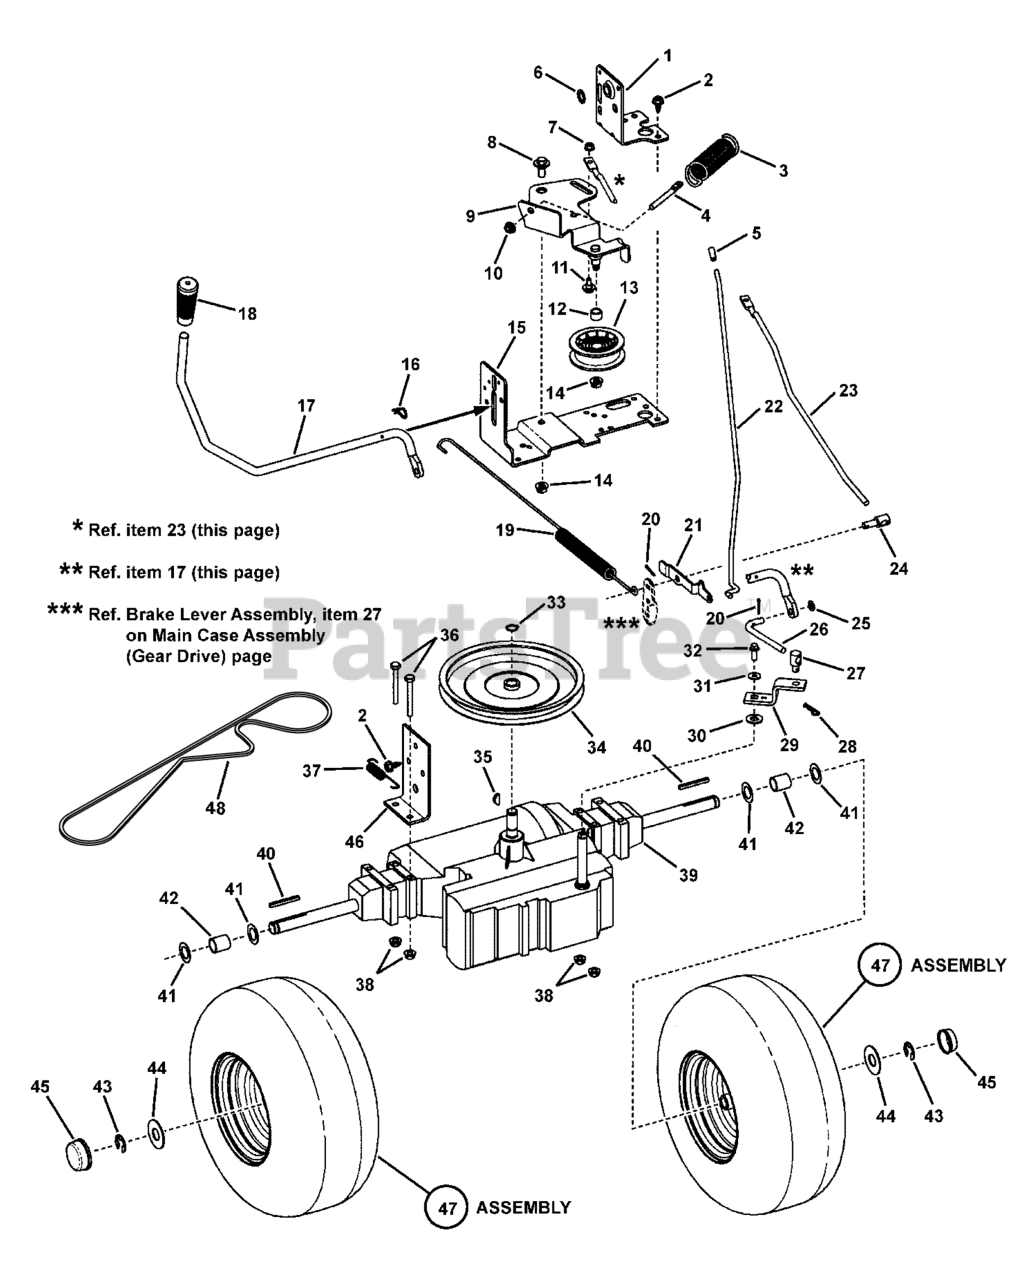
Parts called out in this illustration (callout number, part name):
1	BRACKET - SHIFT PIVOT
2	CAPSCREW 5/16-18
3	SPRING - EXTENSION
4	STUD - SPRING MTG (5/16-18 thread)
6	WASHER, FLAT, .81 X .550 X 16GA
7	1/4-20 HFN
8	SHOULDER BOLT, 0.75 X 0.60 X 3/8-16
9	ASSEMBLY - IDLER ARM
10	HEX NUT, 5/16-18 FLANGE SER YZ
11	SHOULDER BOLT, 1/4-20X3.75
12	SPACER 1/2" TO 17MM
13	IDLER PULLEY - 2.75 DIA.
14	NUT, HEX FLANGE, 3/8-16 NC
15	BRACKET SHIFT RH
16	HAIR PIN, .56D-.092T
17	LEVER - SHIFTER
18	GRIP, .50 SHAFT, TAPERED
19	SPRING - EXTENSION
20	PIN - COTTER, 0.75 X 0.090
21	LATCH - PARKING BRAKE
22	ROD - PARKING BRAKE
23	ROD - CLUTCH
24	ADJUSTING NUT
25	FW, .34X.62X16GA
26	LINK - SHIFT
27	NUT -ADJUSTING (3/8-16 thread)
28	HAIR PIN, .38D-.09T
29	YOKE - SHIFT
30	WASHER, 1.0 X 0.393/0.388SQ.ID X 16GA
31	FW, .26 X.75 X 16GA
32	CAPSCREW 1/4-28 NF FLANGE HEAD
33	SNAP RING, .625-.035T
34	PULLEY - LOW NOISE
35	KEY, WOODRUFF #9
36	HHB, 5/16-18X2.50
37	EXTENSION SPRING
38	NUT, HEX FLANGE LOCK, 5/16-18 NC
39	DANA 6-SPEED TRANS AXLE
40	3/16 SQ KEY - REAR WHEELS
41	HER, FLAT 1.25 X 0.760ID
42	SPACER - 0.875 DIA X 1.12-1.97L
43	E-RING, .750D X .050T
44	FW, 1.862X .765 X 16GA
45	HUB CAP
46	BRACKET - TRANSAXLE RH
47	ASSY, Wheel & Tire 20 x 8.0-8 (incl. 3 items below)
48	BELT, V Motion Drive (4L Sect.; 96.88 E.L.)
